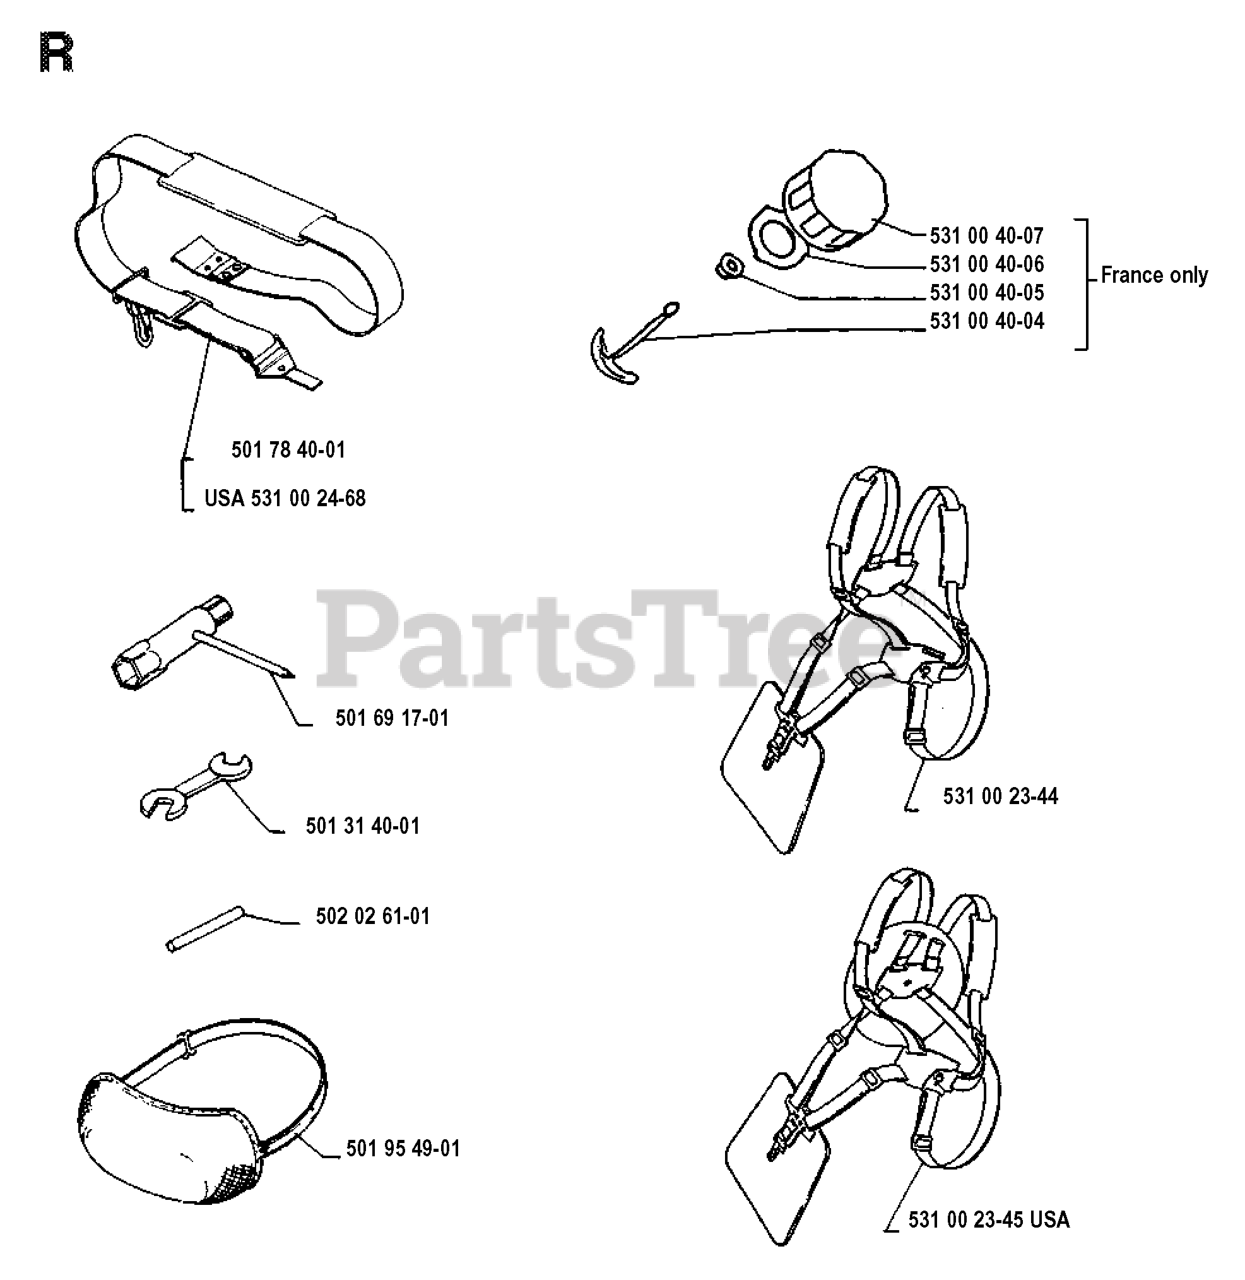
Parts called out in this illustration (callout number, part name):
2	AIR FILTER
5	THROTTLE ROD
6	FILTER HOLDER
7	CARBURETOR
8	STOP LEVER
10	CHOKE CONTROL
11	GUIDE SLEEVE CARB
14	INLET PIPE
